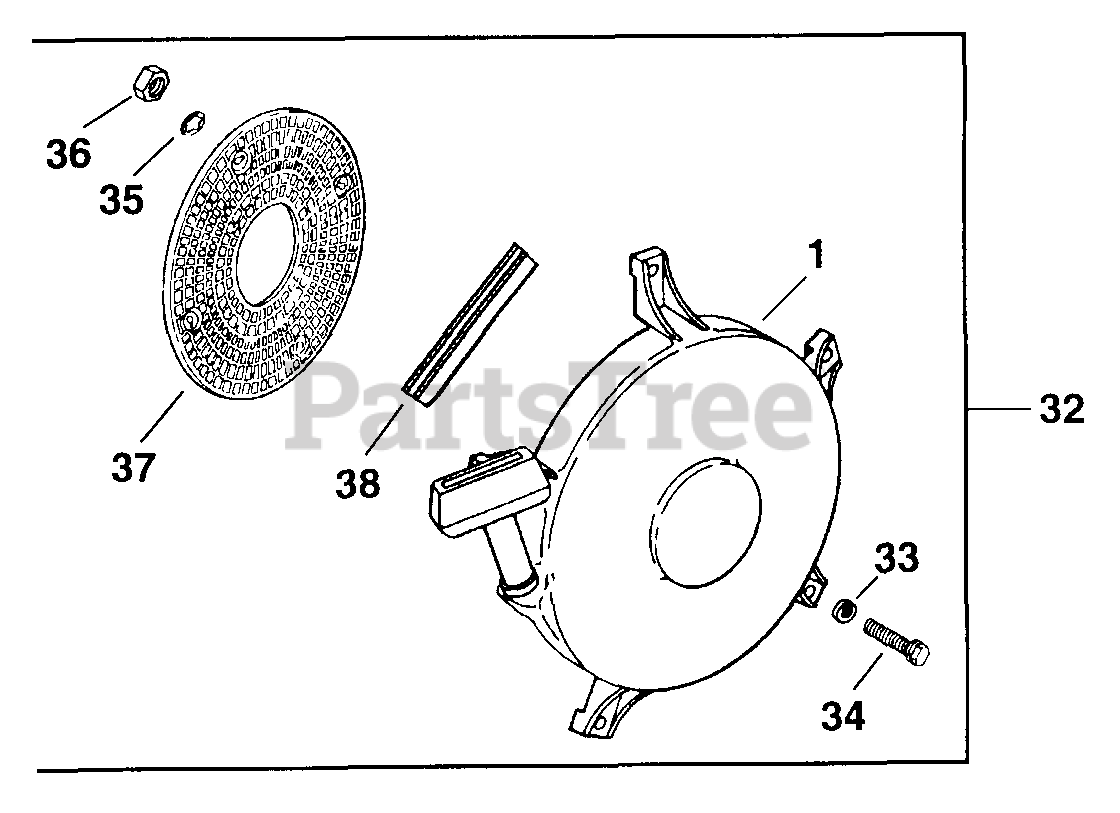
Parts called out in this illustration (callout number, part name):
1	STARTER
32	STARTER - DISCONTINUED
33	WASHER, FLAT 3/16"
34	SCREW, IND SLT HD 10-32X1/2" USE 24 086 55-S
35	WASHER, EXT TOOTH LOCK #10
36	NUT, MACH SCREW #10-32 GRD 2 USE 25 100 18-S
37	SCREEN, GRASS - DISCONTINUED
